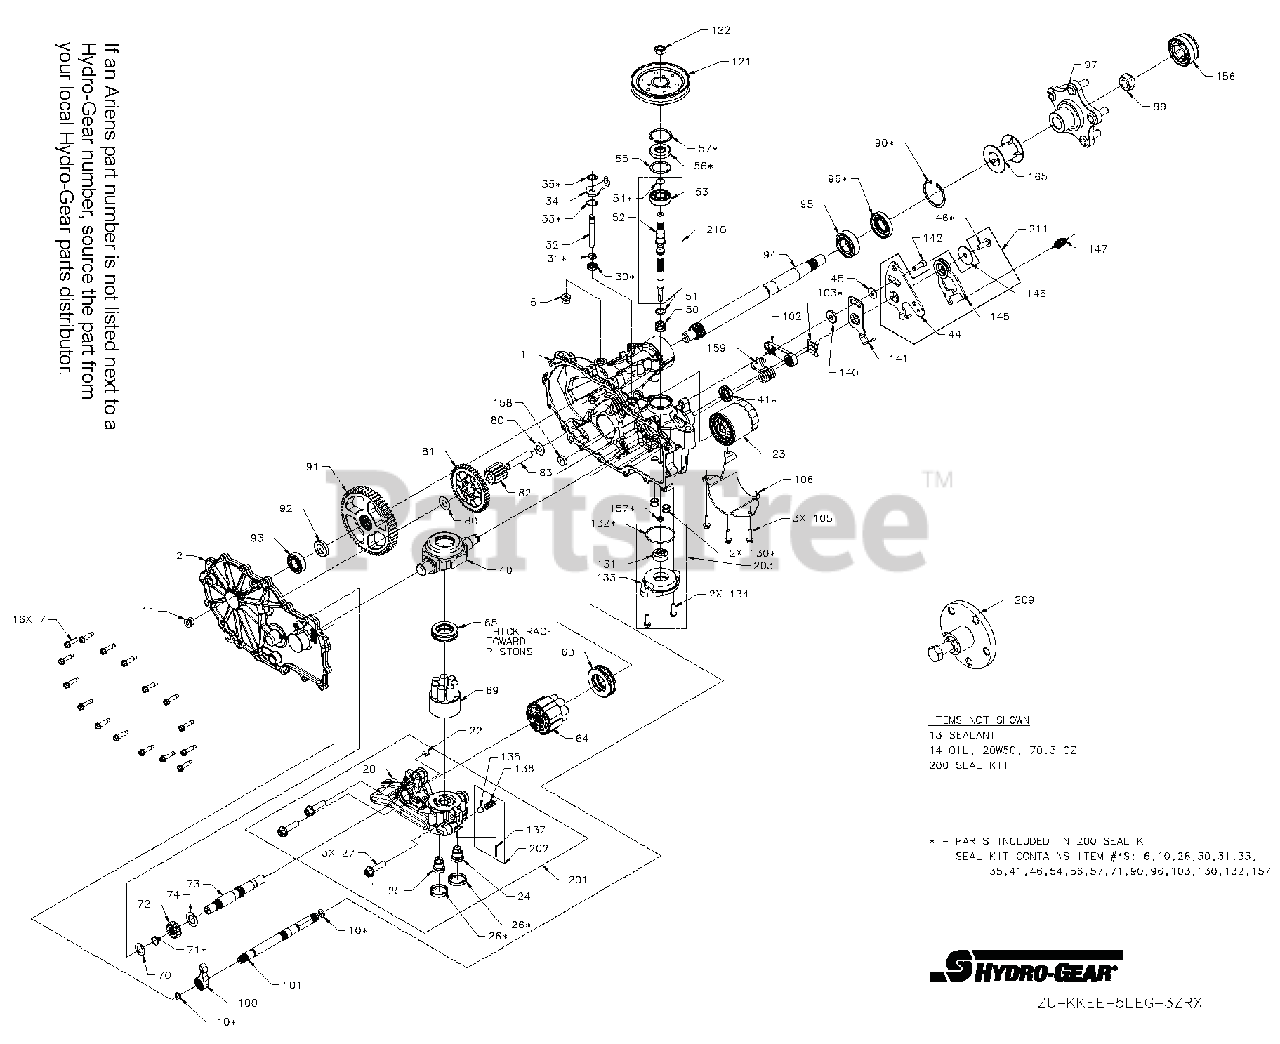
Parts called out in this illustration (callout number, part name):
1	KIT, HOUSING,MAIN,LH,CHRG,CNTL
2	KIT, COVER, SIDE, LH
5	PLUG 9/16-18 (METAL)
11	PLUG 9/16-18 (METAL)
13	SEALANT TUBE 10.1OZ.
20	CENTER SECTION, LH, CHRG
22	PLATE, BYPASS
23	OIL FILTER, TRANSMISSION
24	SHOCK VALVE ASSEMBLY 220 BAR
25	SHOCK VALVE ASSEMBLY 220 BAR
27	HFHCS 3/8-16X1.5 (PATCH)
30	SEAL, LIP .375X.75X.25
31	RING. RETAINING
32	ROD, BYPASS
33	RING, RET .750 INTRNL
34	ARM, BYPASS
35	RING, RTNG .
40	TRUNNION, SWASHPLATE
41	SEAL, LIP 18X32X7
44	ARM, CONTROL, LH
46	TWHCS 5/16-24 X 1.00
50	SPRING, BLOCK
51	WASHER. THRUST .59 X .79 X .04
52	SHAFT, INPUT
54	RING, RET WIRE .561 ID
55	WASHER 1.23X1.56X.04
56	SEAL, LIP 17X40X7
57	RING, RET 1.56 INT
60	BEARING, THRUST
65	BRG, THRUST PLASTIC CAGE
69	ASS'Y, BLOCK 7 PISTON
72	GEAR, 13T, STEEL
73	SHAFT, MOTOR
80	WASHER .5X1.0X.032
82	GEAR, 11T, STEEL
83	JACK SHAFT (PIN)
90	RING, RET 2.06 INT
94	SHAFT, AXLE
95	BEARING, BALL 25.4 X 52 X 15
96	SEAL, LIP
97	KIT, HUB, 5 BOLT
99	NUT, HEX, LOCK 3/4-16
100	PAWL, BRAKE
101	SHAFT, BRAKE
102	KIT HANDLE, ACTUATING
103	CLIP, RETAINING
106	GUARD, FILTER, LH
122	NUT, HEX 1/2-20 PATCH
130	TUBE, CONNECTING
131	GEROTOR ASSEMBLY (1.9 cc/rev)
132	O-RING HYDROGEAR 52250
133	COVER, CHARGE PUMP
136	SPRING, RELIEF
141	ARM, NEUTRAL LEFT
142	SHCS 5/16-24X1 PATCH
145	ASSEMBLY, RTN, CCW
146	WASHER
147	SPRING, HYDROGEAR P/N 51833
157	SEAL, LIP 8 X 12 X 3 VC
158	MAGNET, RING
159	SPRING, TORSION CW
200	KIT, SEAL
201	KIT, CENTER SECTION, LH, CHRG
202	KIT, CHARGE RELIEF
203	KIT, CHARGE PUMP
209	HUB PULLER, 5 BOLT
210	KIT, INPUT SHAFT
211	KIT, RTN, CCW
